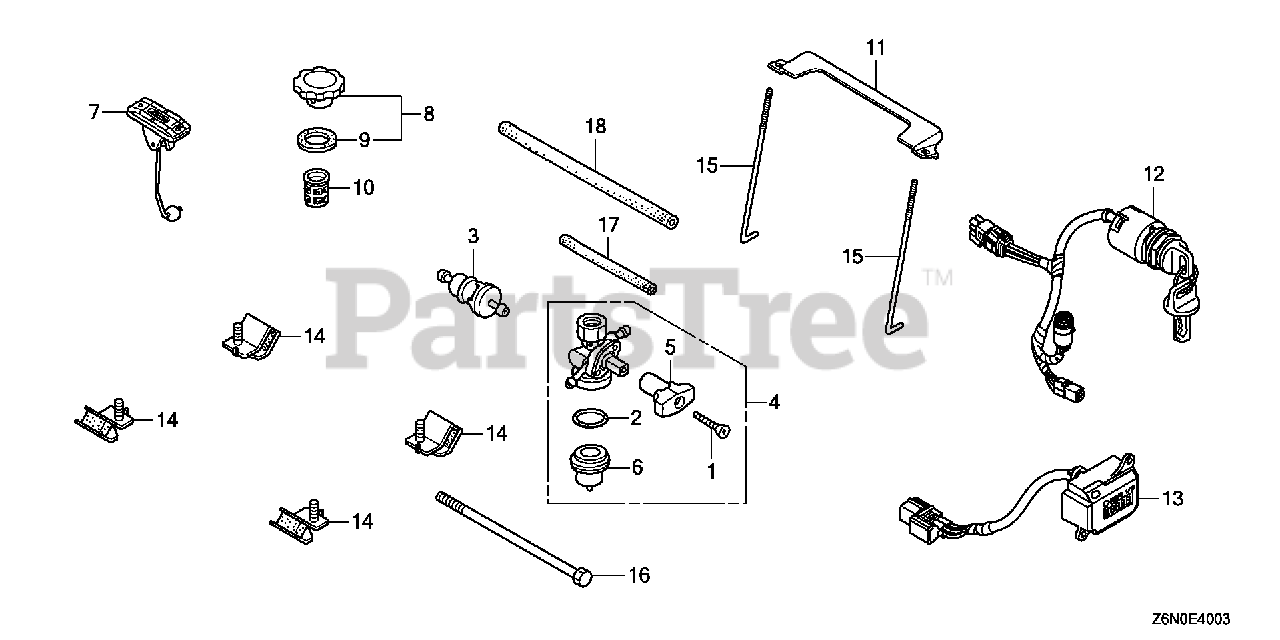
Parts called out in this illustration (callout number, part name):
1	SCREW, OVAL (4X32)
2	GASKET, FUEL STRAINER CUP
3	STRAINER, FUEL
4	PETCOCK ASSY.
5	LEVER, PETCOCK
6	CUP, FUEL STRAINER
7	METER ASSY., FUEL
8	CAP, FUEL FILLER
9	GASKET, FUEL FILLER CAP
10	FILTER, FUEL
11	PLATE, BATTERY SETTING
12	SWITCH ASSY., COMBINATION
13	METER ASSY., HOUR
14	RUBBER (LOWER)
15	BOLT, BATTERY SETTING
16	BOLT, HEX. (10X278)
17	BULK HOSE, FUEL (4.5X3000) (4.5X150)
18	BULK HOSE, FUEL (5.5X3000) (5.5X250)
